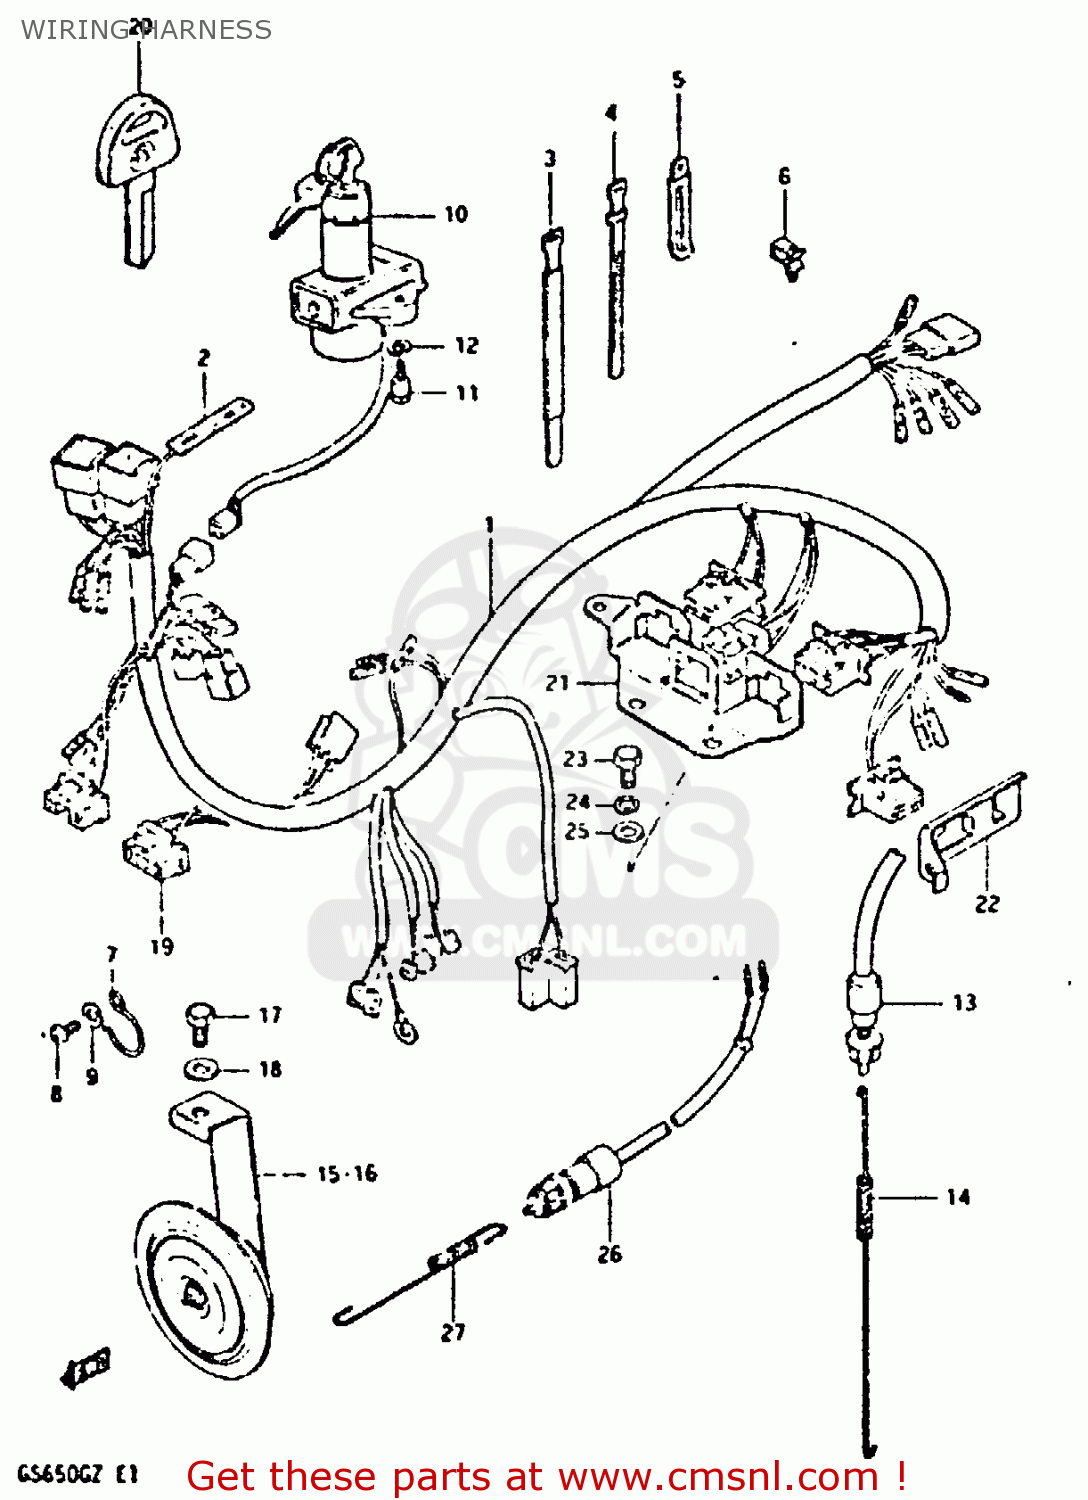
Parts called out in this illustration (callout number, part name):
1	WIRING HARNESS
2	DIODE
3	CLAMP
4	CLAMP
5	CLAMP
6	CLIP
7	GUIDE,WIRING HARNESS
8	SCREW 6X12
9	WASHER
10	LOCK ASSEMBLY,STEERING
11	BOLT
12	LOCK WASHER
13	SWITCH ASSEMBLY,STOP LAMP
14	SPRING
15	HORN
16	HORN ASSEMBLY
17	BOLT 8X12
18	WASHER
19	LEAD WIRE,HEADLAMP
20	KEY,BLANK
21	PLATE, COUPLER HOLDER (A)
22	PLATE, COUPLER HOLDER (B)
23	BOLT
24	LOCK WASHER
25	WASHER
26	SWITCH ASSEMBLY,SIDE STAND
27	SPRING
